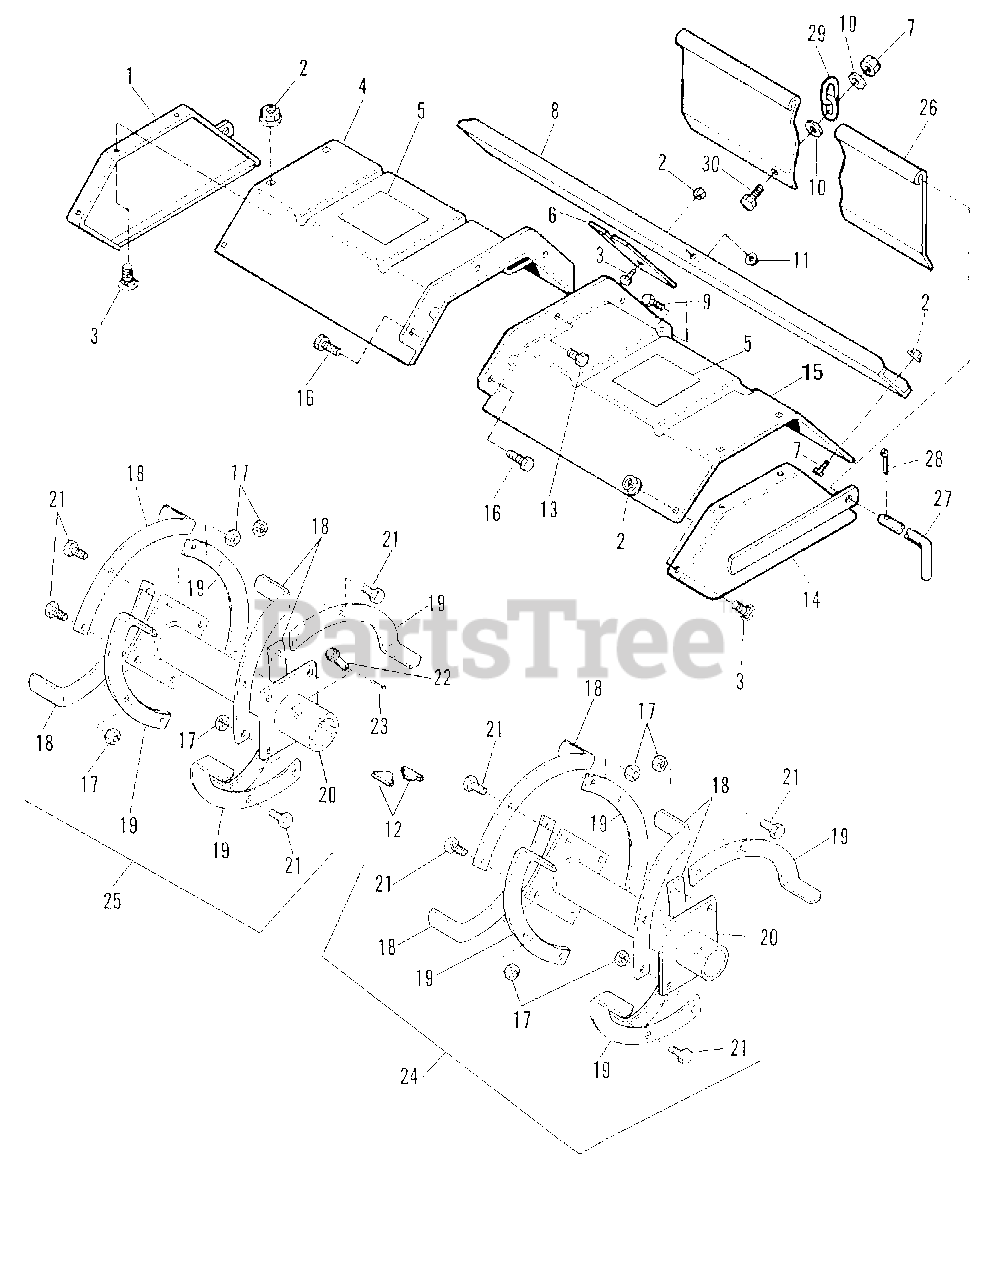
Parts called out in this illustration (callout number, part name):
1	PLATE, End, R.H.
2	LOCKNUT, Flange, 5/16-18
3	CARRIAGE BOLT, 5/16-18 x 5/8
4	DEFLECTOR ASSEMBLY, R.H.
5	DECAL, Safety
6	SHIELD
7	NUT, Hex Head, Flange, 1/4-20
8	CHANNEL
9	CAPSCREW, Hex Head, 3/8-16 x 1
10	WASHER
11	NUT, Hex, Flange, 3/8-16
12	KEY
13	CAPSCREW, Hex Flange Whiz Lock, 3/8-16 x 3/4
14	PLATE, End, L.H.
15	DEFLECTOR ASSEMBLY, L.H.
16	CAPSCREW, Hex, Whizlock, 3/8-16 x 1
17	LOCKNUT, 7/16-20
18	BLADE, Tine, R.H.
19	BLADE, Tine, L.H.
20	HUB & PLATE ASSEMBLY
21	CAPSCREW, Hex Head, 7/16-20 x 1-1/2
22	PIN
23	PIN, Cotter
24	BLADE ASSEMBLY, L.H.
25	BLADE ASSEMBLY, R.H.
26	DEFLECTOR
27	ROD
28	PIN, Cotter
29	CHAIN
30	CAPSCREW, Hex Head, 1/4-20 x 7/8
